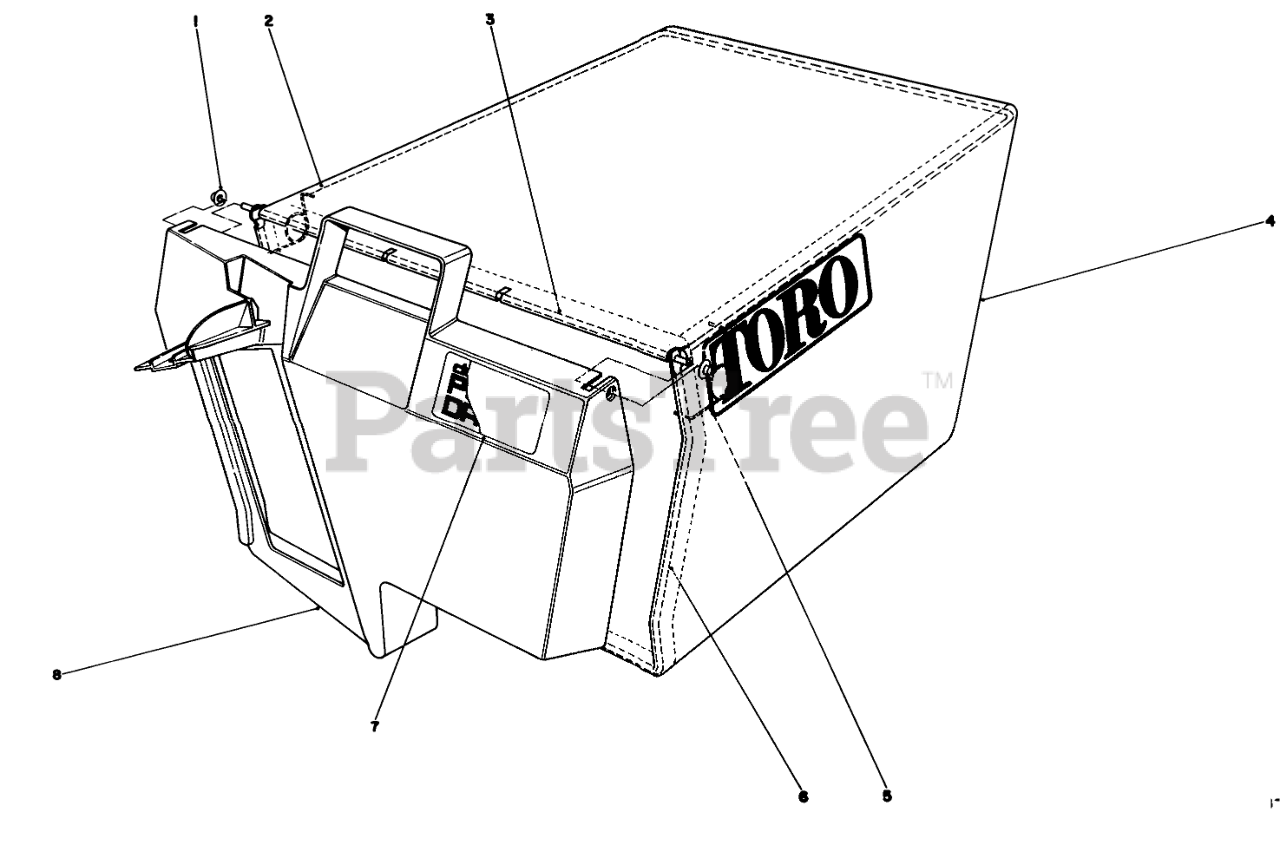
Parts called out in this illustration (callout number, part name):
1	NUT-PUSH
2	FRAME-BAG, UPPER
3	HINGE-DOOR, BAG
4	BAG-GRASS
5	SPRING
6	FRAME-BAG
7	BAG DOOR DECAL
8	DOOR-BAG
